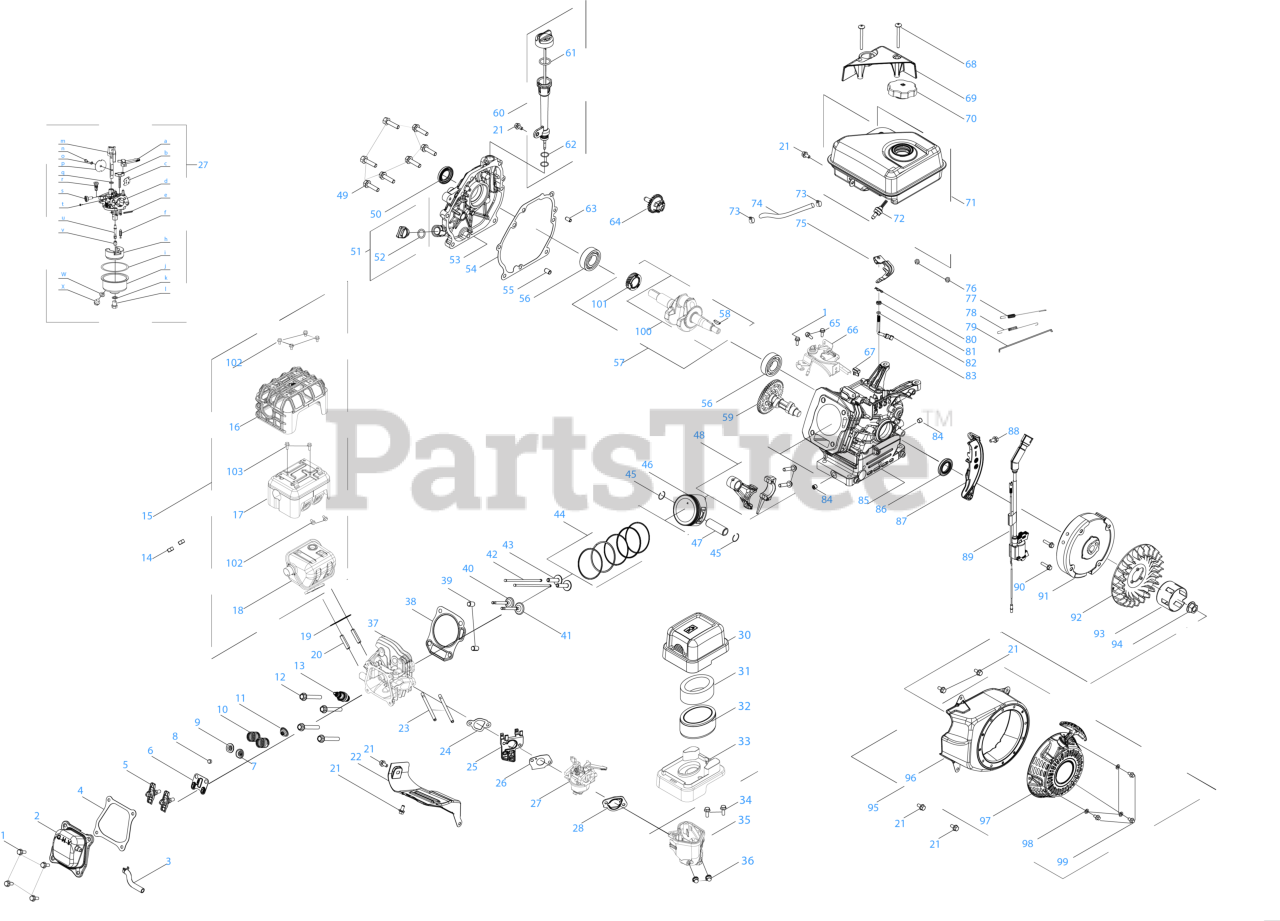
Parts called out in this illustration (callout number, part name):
1	BOLT M6 x 16
2	VALVE COVER
3	BREATHER HOSE
4	VALVE COVER GASKET
5	ROCKER ARM ASSEMBLY
6	ROCKER ARM BASE
7	INTAKE VALVE SPRING RETAINER
8	EXHAUST VALVE ADJUSTER
9	EXHAUST VALVE SPRING RETAINER
10	VALVE SPRING
11	INTAKE VALVE SEAL
12	BOLT-M8-1.25 x 60 GR10.9
13	SPARK PLUG
16	MUFFLER SHIELD
17	INNER MUFFLER SHIELD
18	MUFFLER BODY
19	MUFFLER GASKET
20	STUD M8 x 36
21	BOLT M6-1 x 12 GR8.8
22	AIR SHIELD
23	STUD M6-1 x 110 GR8.8
24	CARBURETOR INSULATOR GASKET
25	CARBURETOR INSULATOR
26	CARBURETOR GASKET
27	Carburetor
28	CARBURETOR GASKET PLATE
30	AIR CLEANER COVER
31	AIR CLEANER WITH PRE-FILTER
32	AIR FILTER
34	SCREW M4x20
35	AIR CLEANER HOUSING
37	CYLINDER HEAD
38	CYLINDER HEAD GASKET
40	EXHAUST VALVE
41	INTAKE VALVE
42	PUSH ROD
44	PISTON RING 4PC SET
45	PISTON PIN SNAP RING
47	PISTON PIN
48	CONNECTING ROD ASSEMBLY
49	BOLT M8-1.25 x 32 GR5.8
50	OIL SEAL 25 x 41.25 x 6
52	O-RING 15.8 x 2.5
53	CRANKCASE COVER
54	CRANKCASE COVER GASKET
55	DOWEL PIN
57	CRANKSHAFT
58	FLYWHEEL KEY
60	DIPSTICK ASSEMBLY
61	DIPSTICK O-RING
62	OIL FILL TUBE O-RING
63	DOWEL PIN
64	GOVERNOR GEAR/SHAFT ASSEMBLY
65	BOLT M6-1 x 12 GR8.8
66	GOVENOR GEAR BRACKET
67	THROTTLE KNOB
68	BOLT M6-1 x 67
69	ENGINE/DIPSTICK COVER
70	FUEL CAP ASSEMBLY-BLACK
72	FUEL INLET NIPPLE
73	HOSE CLAMP
74	FUEL HOSE (6.3x12.5x123MM)
75	GOVERNOR LEVER
77	GOVERNOR SPRING
78	THROTTLE RETURN SPRING
79	GOVERNOR ROD
80	COTTER PIN
81	GOVERNOR SEAL
83	GOVERNOR SHAFT
84	OIL DRAIN PLUG
86	OIL SEAL-25 x 41.25 x 6
87	LOWER SHIELD
88	SCREW M6-1 x 20 CL5.8
89	IGNITION COIL
90	BOLT M6-1 x 25 GR8.8
92	COOLING FAN
93	STARTER CUP
94	FLYWHEEL NUT
95	Recoil Starter
96	BLOWER HOUSING
97	RECOIL STARTER
98	RECOIL FLAT WASHER
99	BOLT M6 x 10
100	Crankshaft
101	DRIVE TIMING GEAR
102	BOLT M5-.8 x 8 CL10.9
103	BOLT M5-.8 x 12 CL10.9
